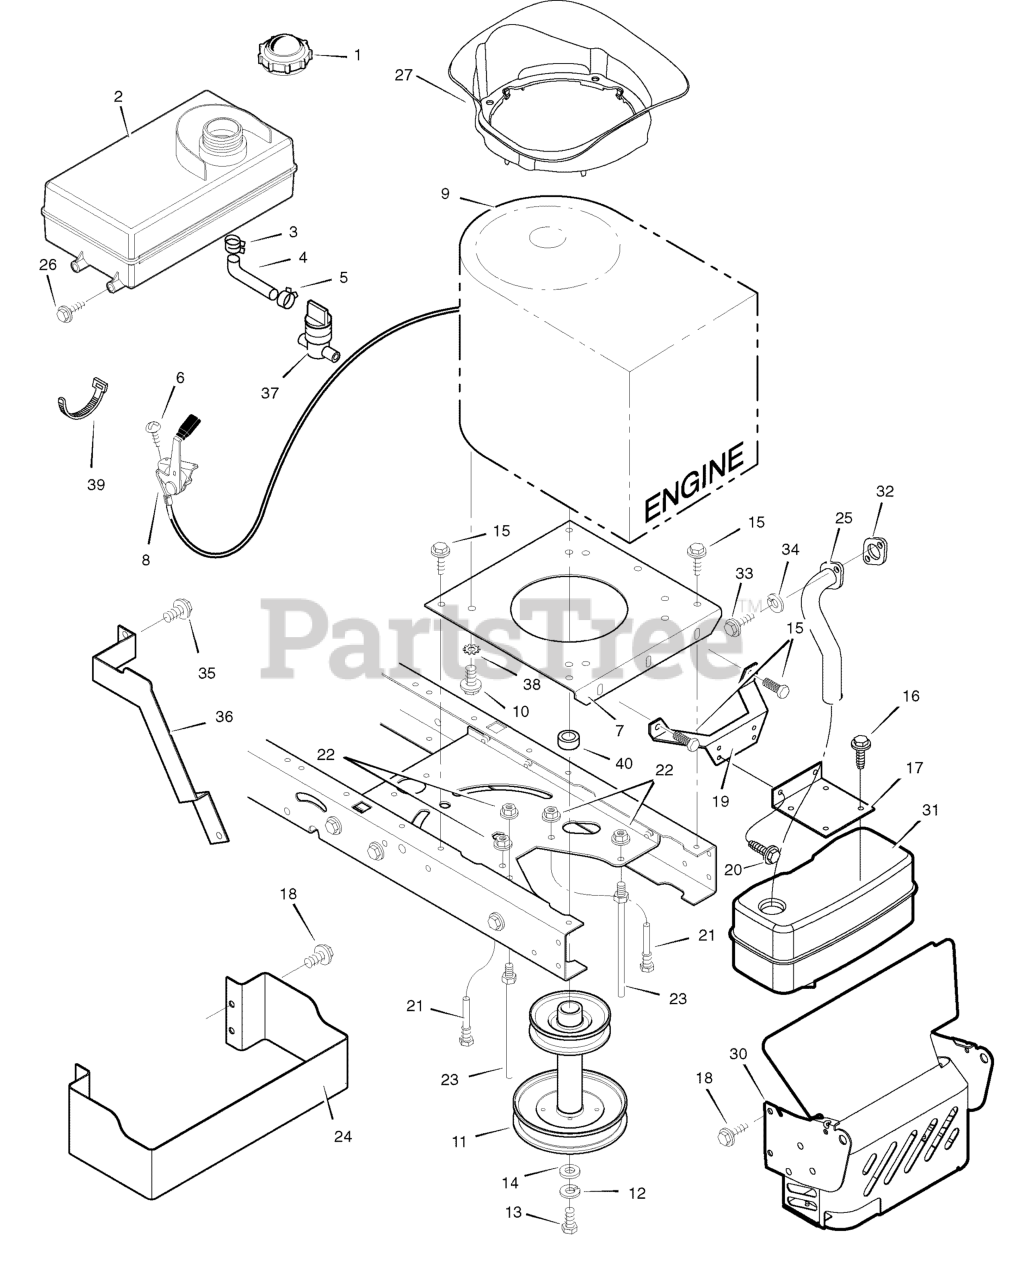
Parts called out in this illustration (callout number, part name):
1	FUEL CAP
2	FUEL TANK
3	HOSE CLAMP
4	FUEL LINE (Cut to length)
5	HOSE CLAMP
7	PLATE, Engine
8	THROTTLE CONTROL
9	ENGINE, Briggs & Stratton *
10	BOLT, Engine Mount
11	STACK PULLEY ASSEMBLY
12	LOCKWASHER
13	BOLT, Hex
17	BRACKET, Muffler
19	BRACKET, Muffler Mount
21	GUIDE, Belt
22	NUT, Flange
23	GUIDE, Belt
24	GUARD, Heat Shield
25	EXHAUST TUBE, Single
30	SHIELD, Heat
35	BOLT, Washer Hex Head
36	GUARD, Exhaust Pipe
37	VALVE, Fuel Shut-Off
38	WASHER, 3/8-5/8 Star
39	STRAP, Tie
40	SPACER, Engine
